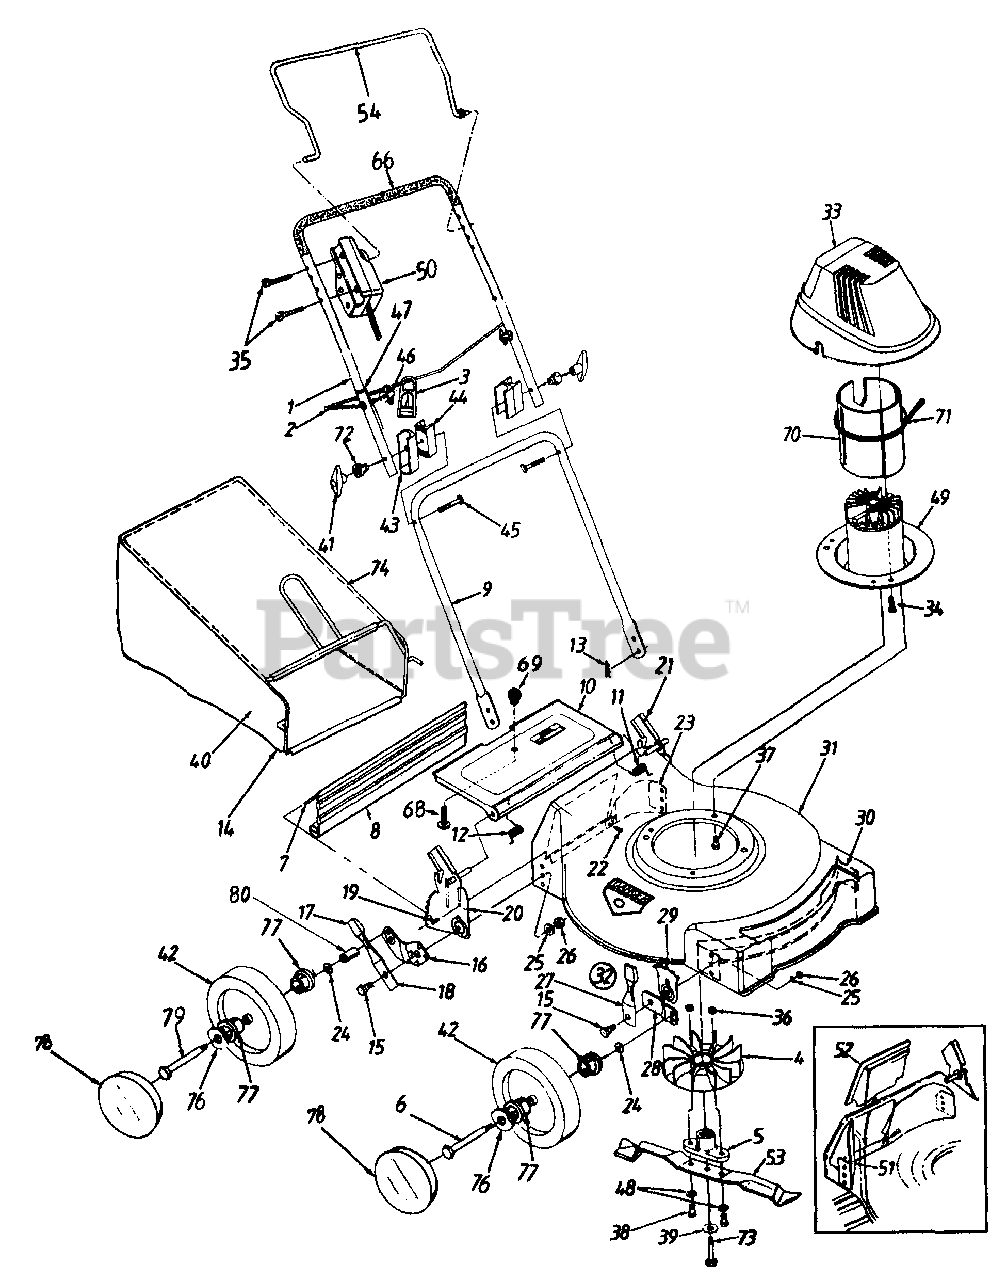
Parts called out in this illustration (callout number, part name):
3	Strain-Relief Cord
5	Blade Adapter
7	Rear Flap Wire
12	Door Spring (R.H.)
13	Hairpin Clip
16	Pivot Bar (R.H.)
17	Spring Lever Knob
19	Hex AB-Tap Scr.
20	Handle Bracket Ass'y. (R.H.)
21	Handle Bracket Ass'y. (L.H.)
22	Torx . Mach. AB-Tap Scr.
25	Bell Washer .39" I.d. x 1.38" O.D.
26	Hex Nut 3/8-16 Thd.
27	Spring Lever Ass'y. W/Knob
29	Height Adj. Plate
34	Scr. #10-24 x .75" Lg.
35	C-Sunk Scr. 1/4-20 x 1.8" Lg.
36	Hex Nut 3/8-24 Thd.
37	Hex TT-Tap Scr. 3/8-16 x 1" Lg.
38	Hex Bolt 3/8-24 x 1.25" Lg.
39	Bell Washer .396" I.D. x 1.14"
40	Grass Bag w/Icon
41	Plastic Knob
42	Wheel Ass'y. Comp.
43	Upper Handle Insulator
44	Lower Handle Insulator
45	Carriage Bolt 5/16-18 x 3" Lg.
46	Knob - Plastic
47	Cable Tie
48	Bell Washer 3/8" I.d.
49	Motor, Cord & Switch Ass'y.
50	Cord & Switch Ass'y. Comp.
53	19" Mulching Blade
68	Truss Scr. #10-24 x .38" Lg.
70	Cable Tie
71	Insulator Motor Hsg.
72	Insulator Knob
73	Hex Bolt 3/8-24 x 2.5"
77	Ball Bearing
78	Hub Cap
79	Rear Axle Bolt
80	Spacer
